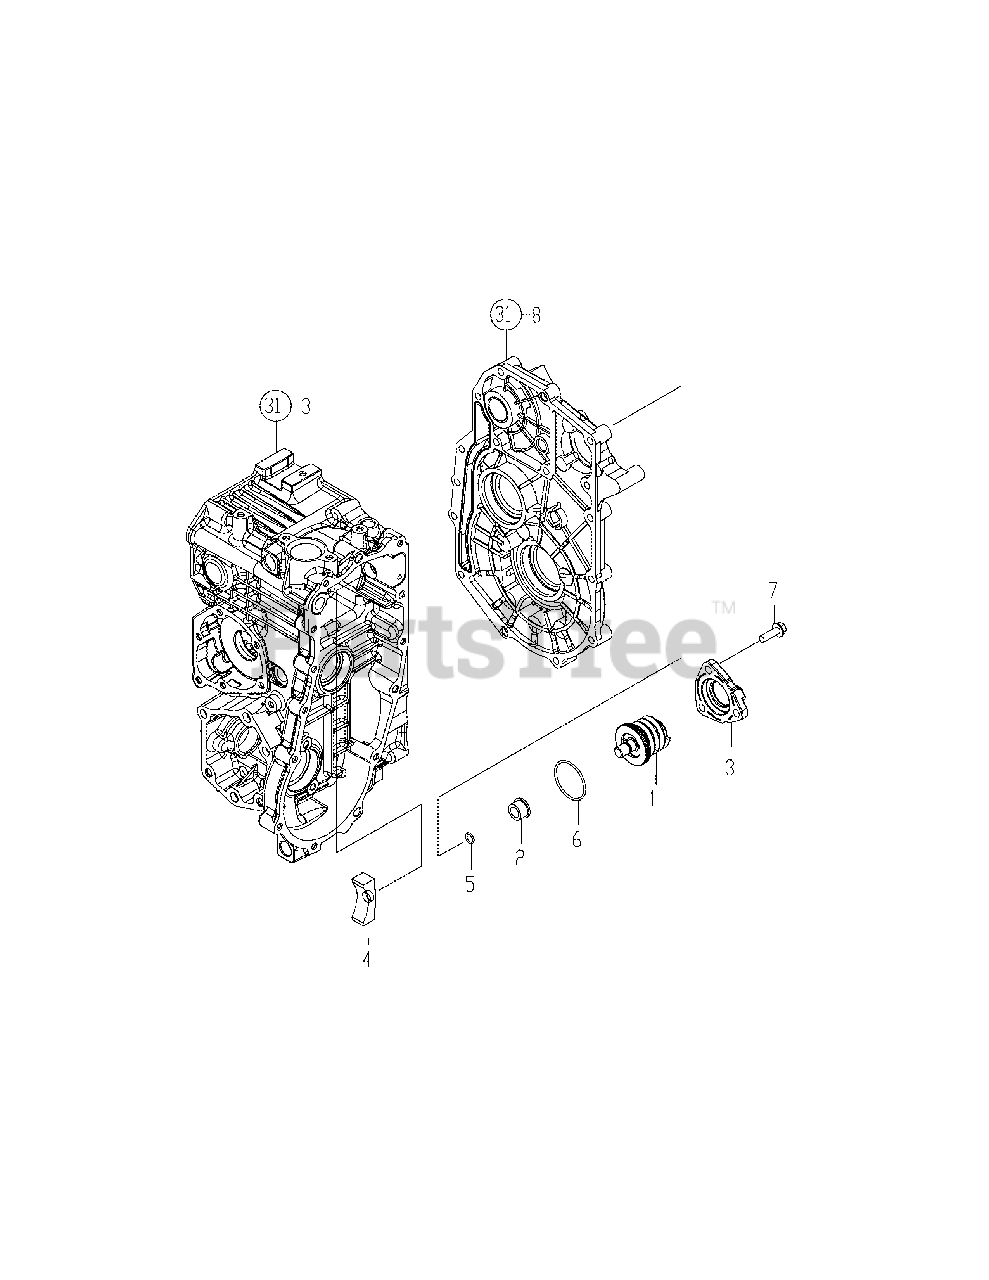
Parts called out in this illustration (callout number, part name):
1	Brake Kit, Pto
2	Collar, Brake Pin
3	Cover, Pto Brake
4	Shoe, Pto Brake
5	Packing, P 10.0
